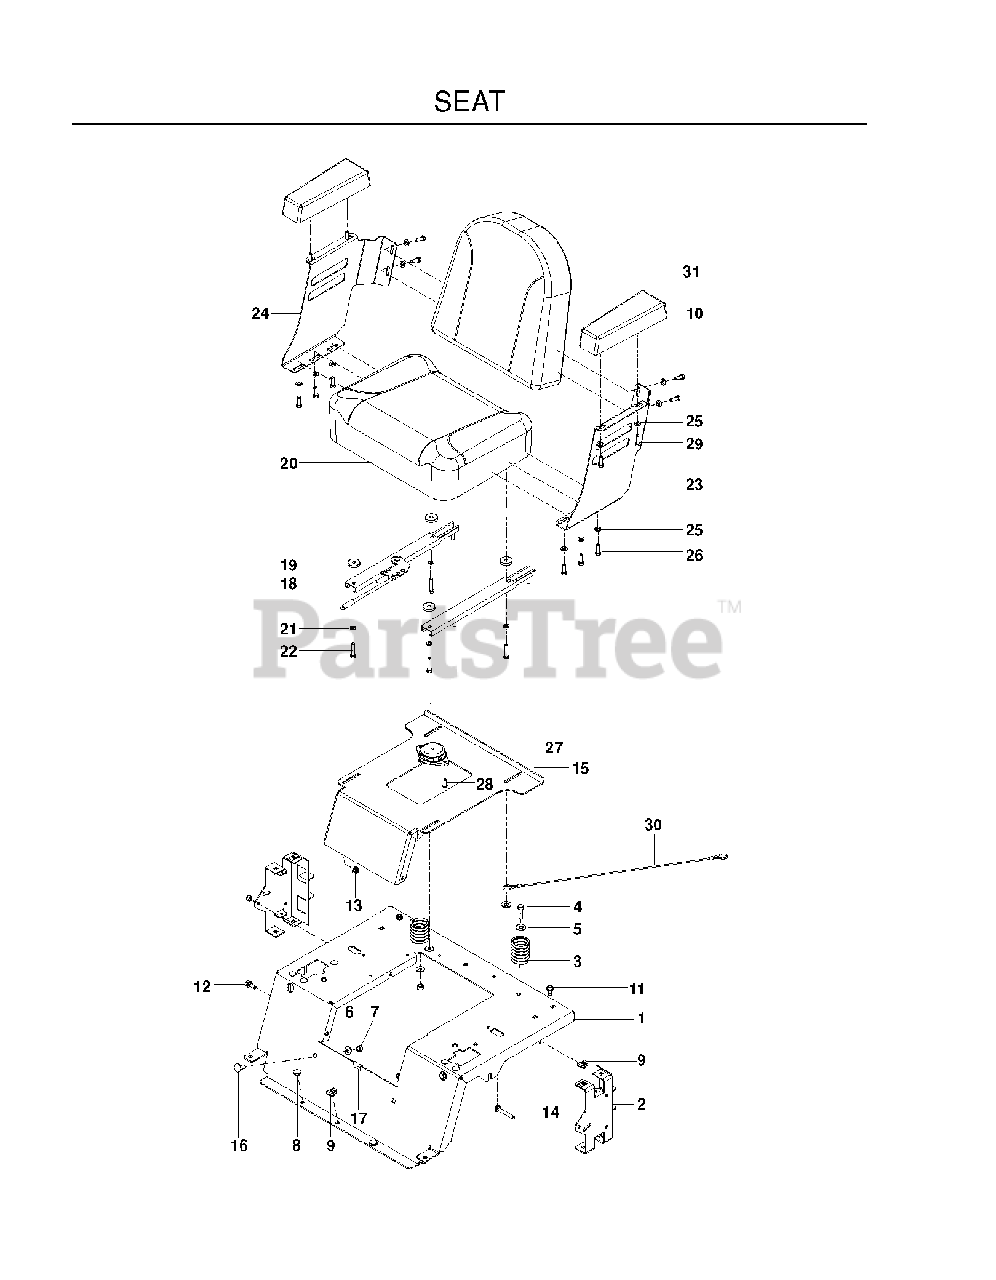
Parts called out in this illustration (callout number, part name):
1	SUPPORT, SEAT, BLUE
2	SUPPORT, REAR SEAT, BLACK
3	SPRING, SEAT
4	HCS 3/8C X 1 1/4 GR5
5	WASHER 3/8 FLAT
6	WASHER 3/8 SAE FLAT
7	NUT 3/8-16 NYLOC
8	GROMMET, BUMPER
9	U-CLIP 5/16-18 NUT RETAINER
11	BOLT 5/16-18 X 3/4
12	SB 5/16-18 HEX HD GD5, BLK ZN
13	5/16-18 NYLOC FLANGE NUT
14	RHSNB 5/16-18 X 2-1/2 GR5 ZD
15	PAN, SEAT, BLUE
16	RHSNB 3/8C X 1
17	CLIP-1.06
18	SEAT SLIDE (SET)
19	WASHER NYLON
20	SEAT BOTTOM
21	WASHER 5/16 LOCK
22	5/16-18X1-1/2 HHB GR5WNY
25	FLAT WASHER 5/16 SAE
26	5/16-18X1 HHB G5W/NY
27	SEAT SWITCH MILSCO
28	SCR 1/4-20X3/4 SLTD RDHD GR2ZD
29	HCS 5/16C X 1
30	SEAT LANYARD
31	SEAT BACK
